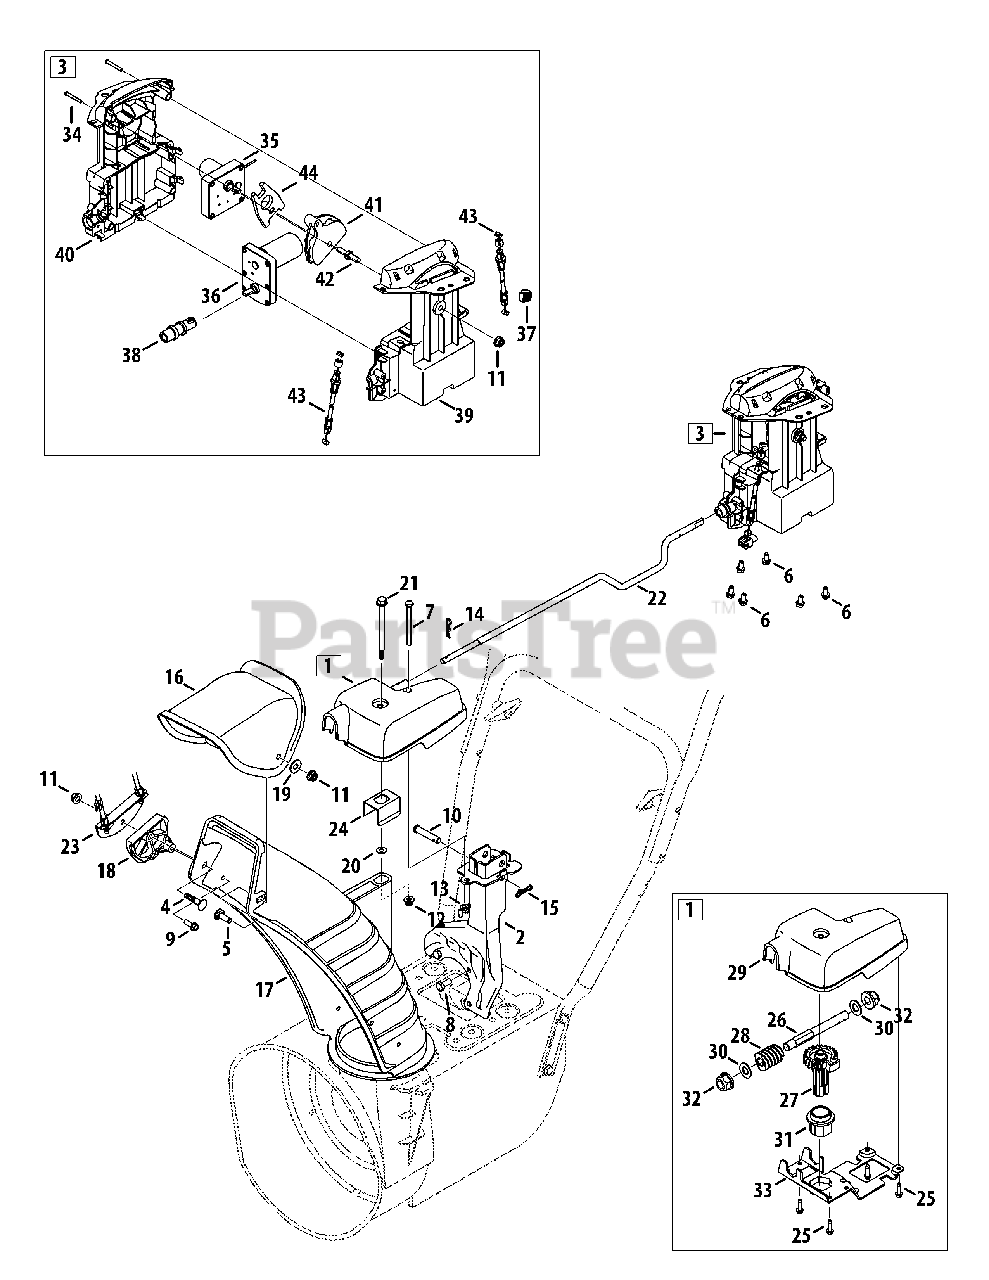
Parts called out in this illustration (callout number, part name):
1	Gearbox Assembly, Chute Rotation
2	Chute Support Bracket
3	Chute Assembly, 4-Way Elec.
4	Bolt, Carriage, 5/16-18 x 1.50
5	Bolt, Carrier, 5/16-18 x 1.00
6	Screw, HL, 1/4-15 x 0.50
7	Hex Head Screw, 1/4-20 x 3.00
8	Hex Head Screw, 5/16-24 x .750
9	Screw, HL, 1/4-15 x 0.750
10	Clevis Pin, 3/8 x 1.87
11	Nut, Flangelock, 5/16-18
12	Nut, Flangelock, 1/4-20
13	Wing Nut, 1/4-20
14	Internal Cotter Pin
15	Bow-Tie Cotter Pin
16	Chute, Upper
17	Chute, Lower
18	Cable Guide, Chute Tilt
19	Washer, Flat, .349 x .879
20	Washer, Flat, .25 x .630
21	Screw, Shoulder, .312 x 3.5 x 1/4-20
22	Chute Crank Rod
23	Cable Bracket
24	Chute Bracket
25	Screw, 12-16 x .75
30	Flat Washer, .510 x 1.00 x .060
31	Flange Bearing, 1.00 ID
32	Flange Bearing, .50 ID
33	Gear Bracket
34	Screw, #10-16 x 1.25
35	Chute Pitch Motor
36	Chute Rotation Motor
37	Cable Clip
38	Electric Chute Coupler
39	Housing, LH
40	Housing, RH
41	Cable Guide
42	Hex Screw, 5/16-18 x .75
43	4-Way Cable
